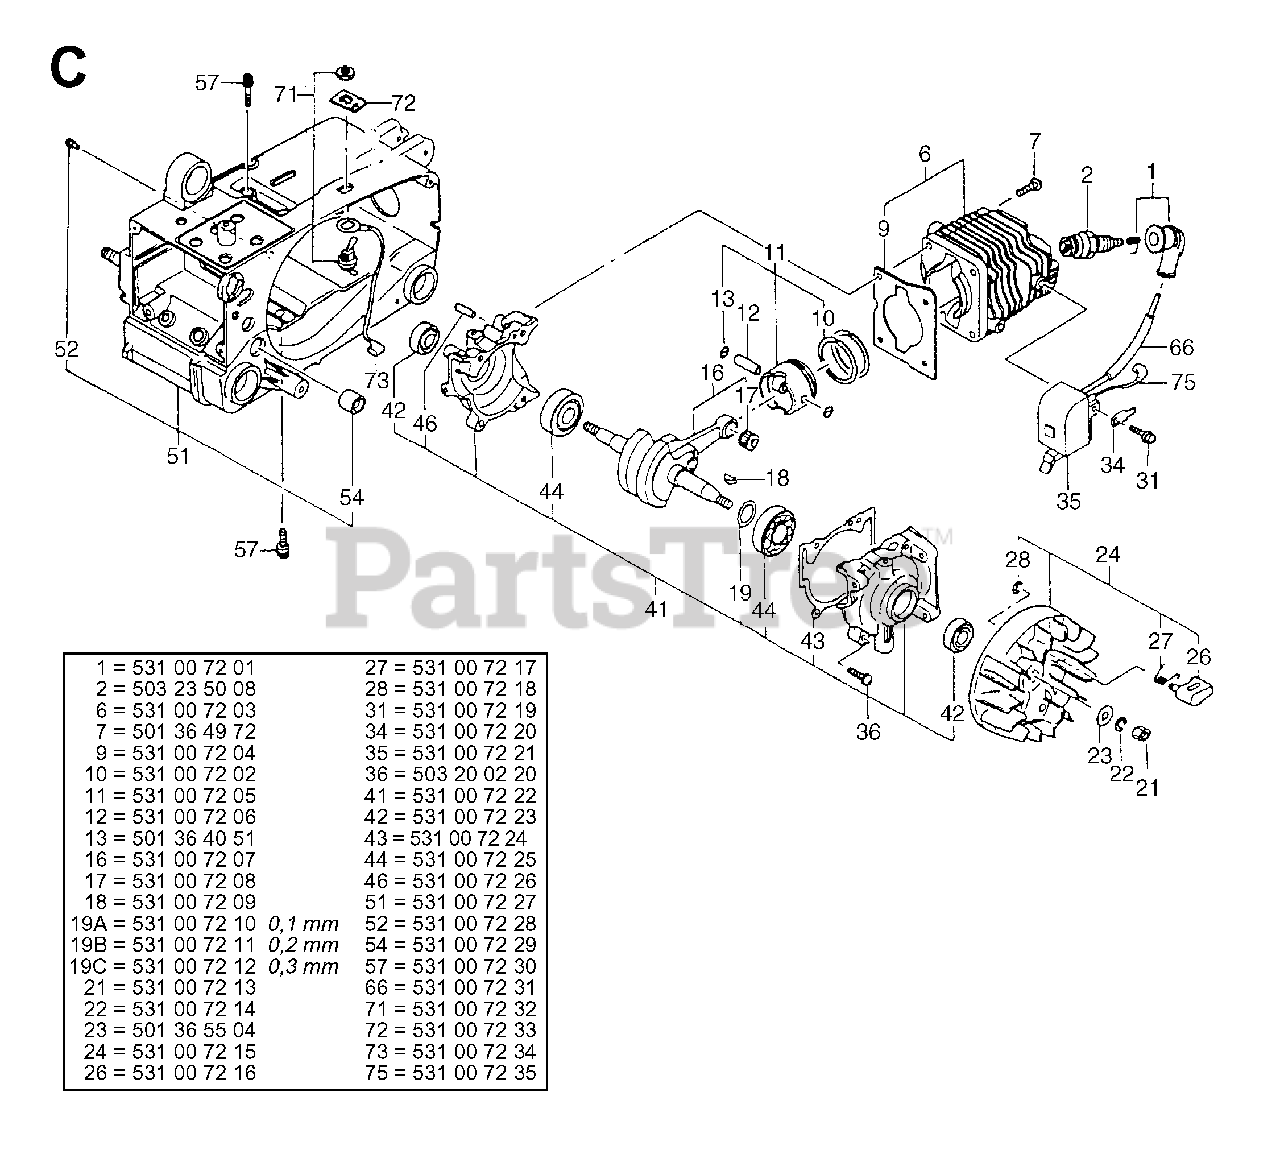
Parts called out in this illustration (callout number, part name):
1	SPARK PLUG CONNECTION
2	SPARK PLUG CJ8 NLA
10	PISTON RING
12	PISTON BOLT
16	CRANKSHAFT
17	NEEDLE BEARING
19A	WASHER
19B	WASHER
19C	WASHER
28	RETAINING RING
35	IGNITION COIL
41	CRANKCASE
51	CRANKCASE
66	PROTECTOR
71	STOP SWITCH
